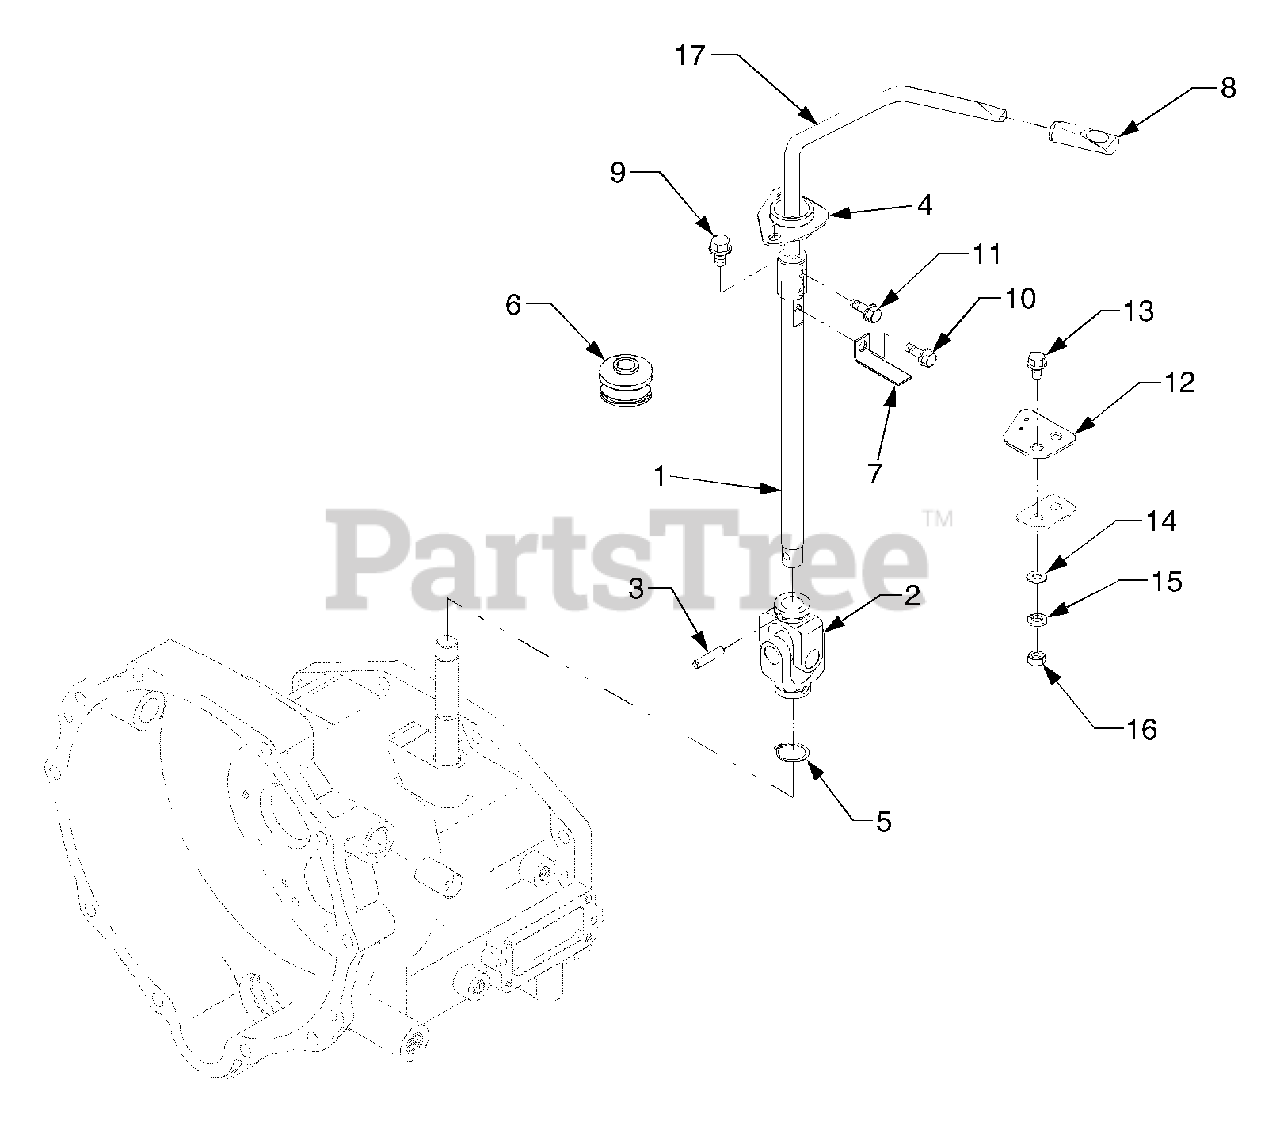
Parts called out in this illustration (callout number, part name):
1	Lever, Shuttle
2	Joint, Universal
3	Pin, Straight
4	Flange, Bearing
6	Boot 1 (Shuttle Lever)
7	Bracket, Switch
8	Grip (Shuttle Lever)
14	Washer, Plain
15	Washer, Spring
17	Lever 2, Shuttle
